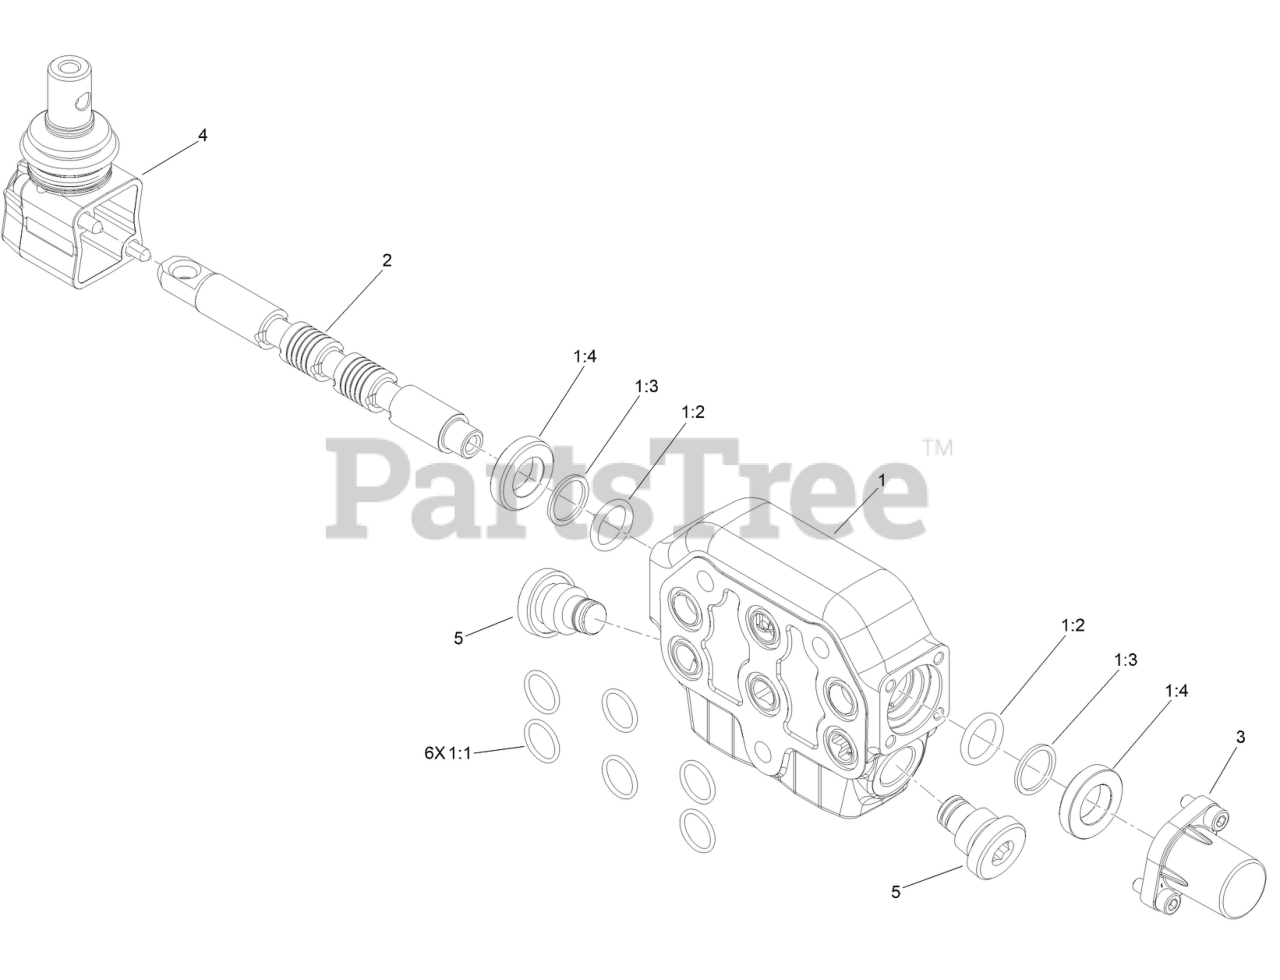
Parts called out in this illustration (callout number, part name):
1	SECTION-WORKING
1:1	O-RING
1:2	SEAL-VALVE
1:3	SEAL-VALVE
1:4	SEAL-VALVE
2	VALVE-SPOOL
3	KIT-CONTROL
4	LEVER-VALVE
